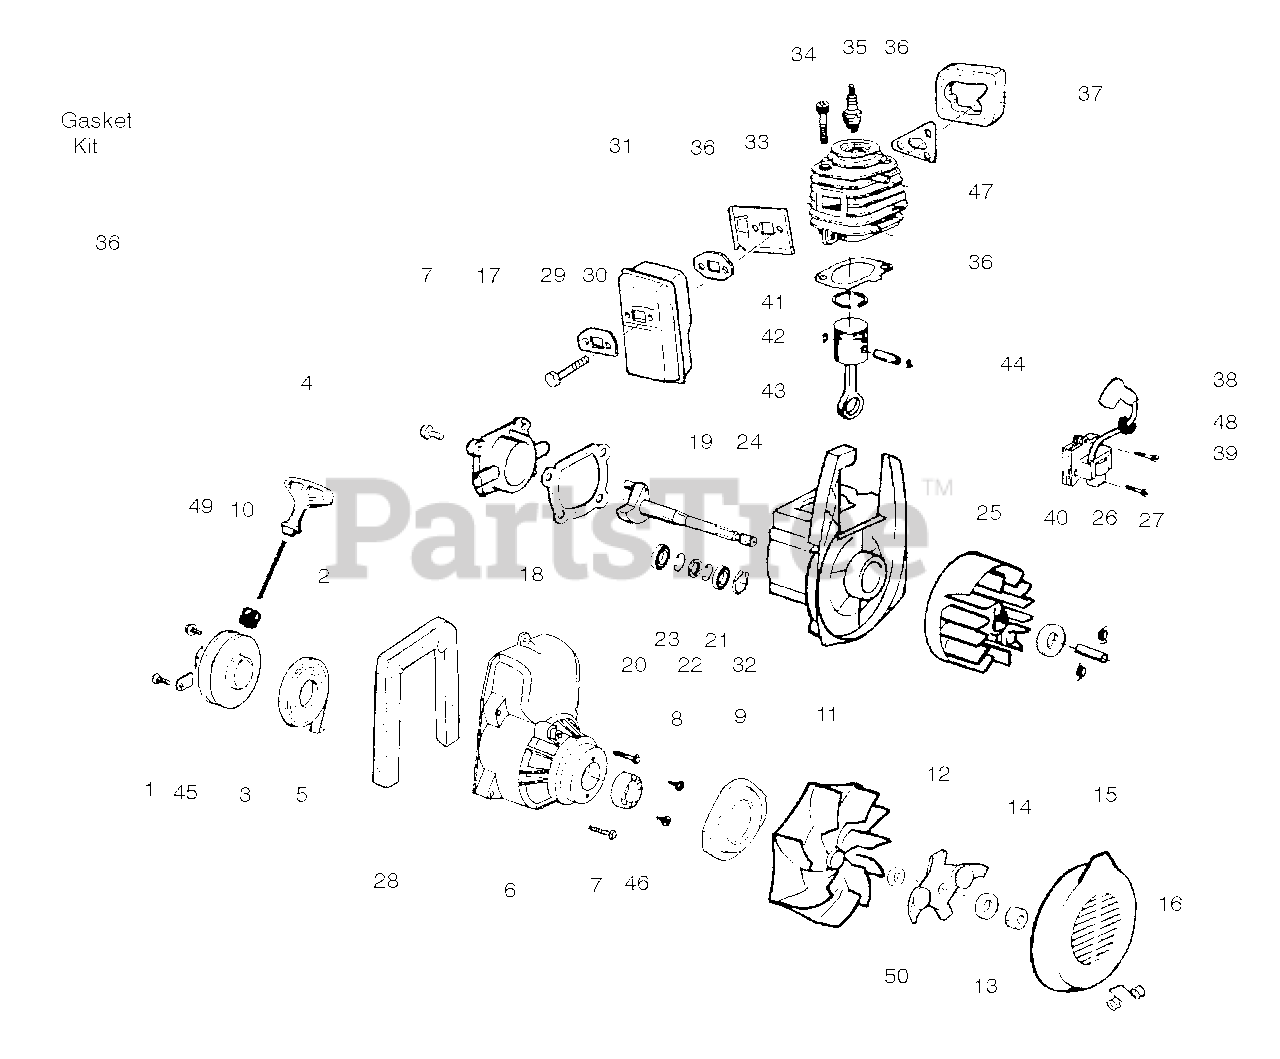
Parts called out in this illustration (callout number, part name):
2	Rope Kit
3	Starter Pulley Kit
4	Starter Handle
5	Starter Spring
6	Fan Housing
7	Screw
11	Impeller
12	Mulch Blade Ass'y. Model 2000
13	Washer-Flat Model 1850
15	Inlet Door
16	Spring-Return Cover
17	Crankcase Cover
18	Gasket-Crankcase Shroud
19	Crankshaft Ass'y.
20	Inner Bearing
21	Outer Bearing
22	Crankcase Seal
23	Retaining Ring
24	Crankcase Ass'y.
25	Flywheel Ass'y.
26	Spring-Starter Dog
27	Flywheel Spacer
28	Foam Seal
29	Muffler Bolt
30	Muffler Cover Plate
31	Muffler Ass'y.
32	Retainer Ring-C'chaft
33	Muffler Shield
35	Spark Plug (RCJ-8Y)
36	Gasket Kit
38	Ignition Module
41	Piston Ring (2)
42	Retainer
43	Connecting Rod Ass'y.
44	Piston Kit
45	Pulley Retainer
46	Bearing
47	Cylinder
48	Grommet-Ign. Module
49	Screw-Starter Pulley
50	Washer-Belleville
